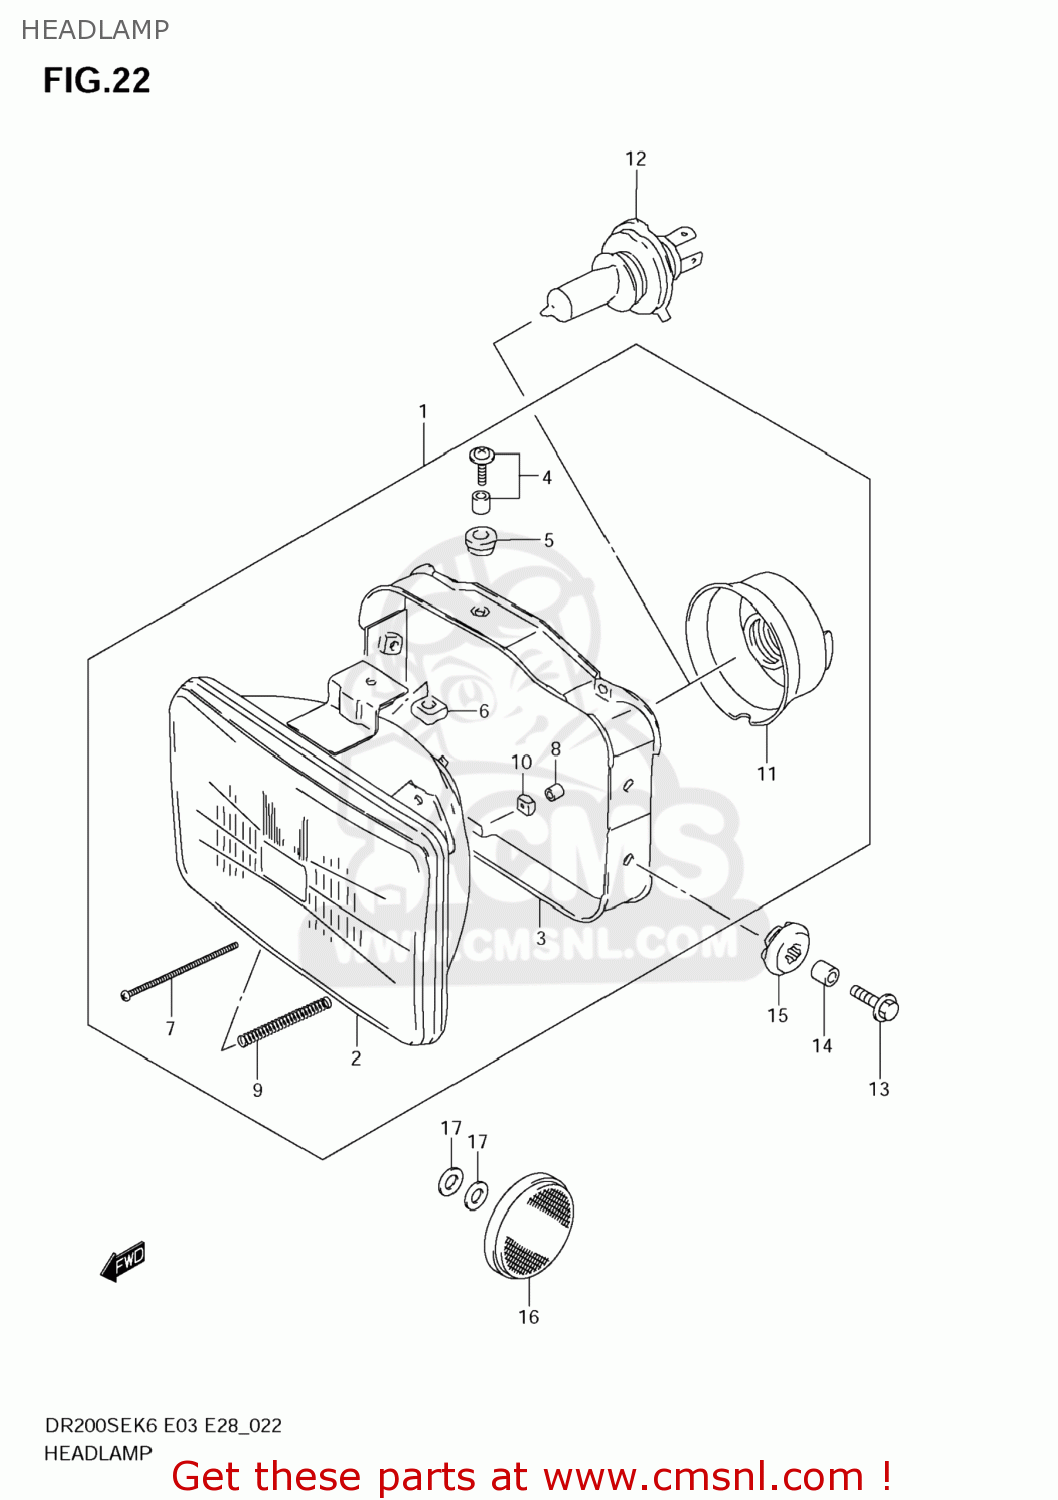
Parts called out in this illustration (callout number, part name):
1	HEADLAMP ASSY
2	LAMP UNIT
3	HOUSING
4	SCREW,MOUNTING
5	CUSHION
6	NUT
7	SCREW
8	CAP,SCREW
9	SPRING
10	NUT,HEADLAMP ADJUST
11	COVER,SOCKET
12	BULB(12V60/55W,H4)
13	BOLT(6X20)
14	SPACER(6.5X9X9)
15	CUSHION
16	REFLECTOR,REFLEX
17	WASHER(5X10X1.0)
